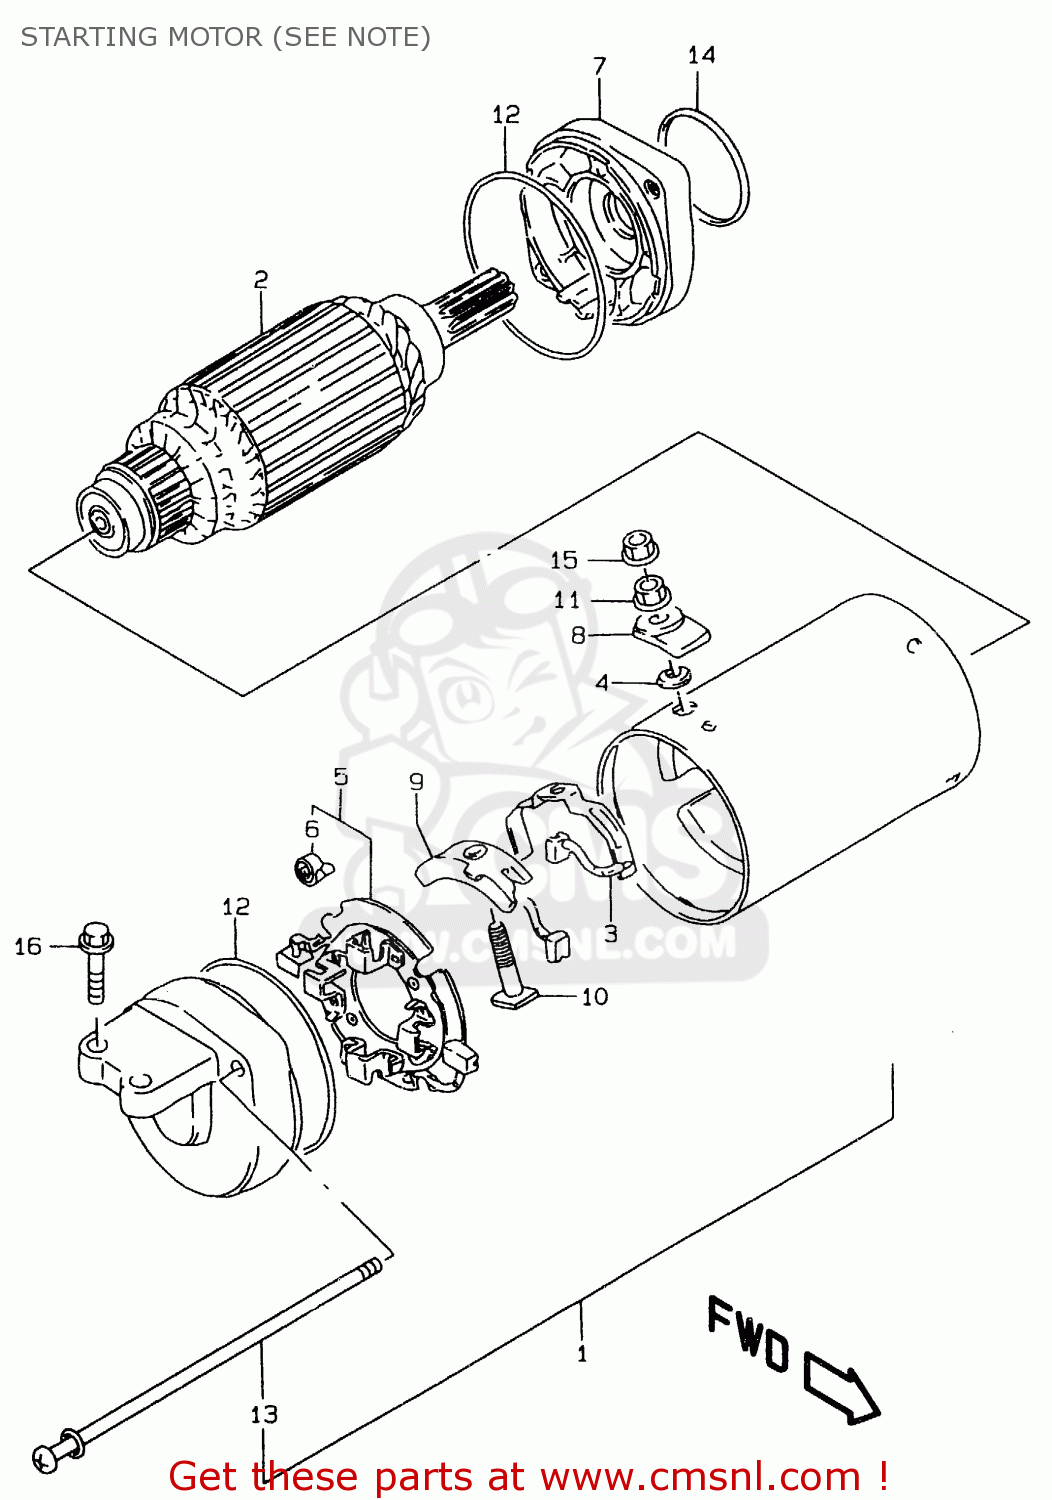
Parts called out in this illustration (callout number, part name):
1	MOTOR ASSY ,STARTING
2	ARMATURE
3	TERMINAL SET,BRUSH
4	GASKET (NAS)
5	HOLDER SET,BRUSH(-)
6	SPRING
7	BRACKET SET
8	BUSHING
9	BUSHING
10	BOLT
11	NUT
12	O RING
13	BOLT
14	O-RING (D:2.1 ID:34.7)
15	NUT
16	BOLT
